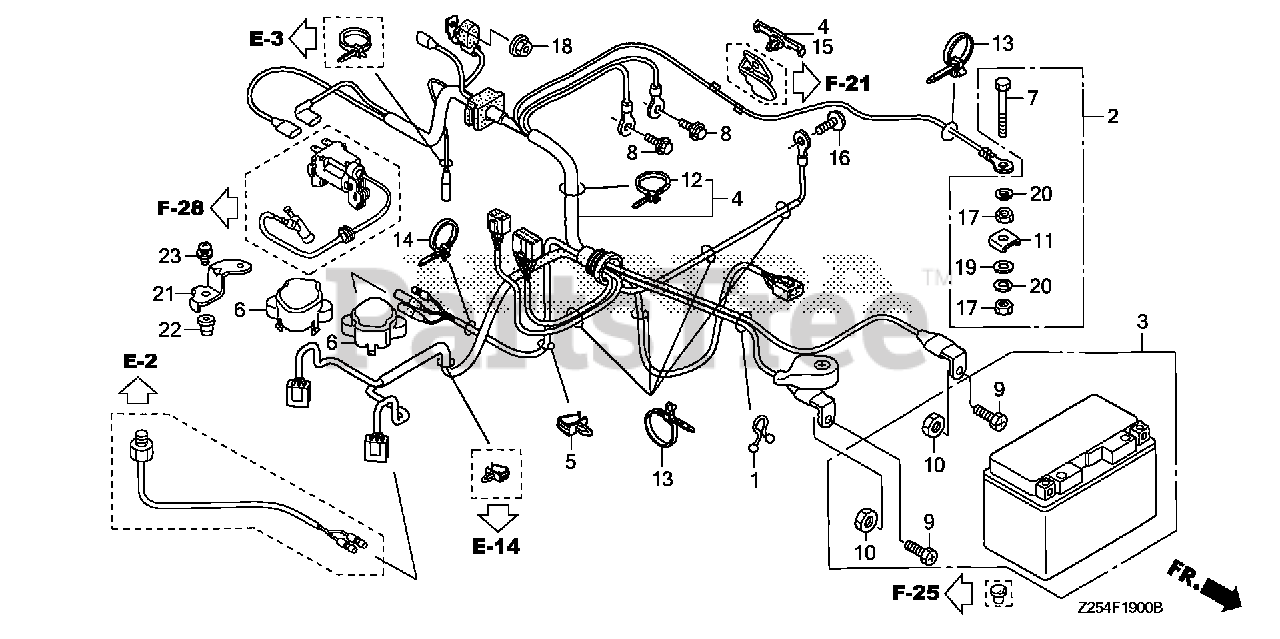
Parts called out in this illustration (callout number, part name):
1	CLAMP, FUEL HOSE (18.5MM)
2	TERMINAL SET, GROUND
3	BATTERY (YTZ14S) (YUASA) (MSDS)
4	WIRE HARNESS ASSY., ENGINE
5	CLIP B, HARNESS
6	COVER, THROTTLE MOTOR
7	BOLT, HEX. (6X28)
8	BOLT, FLANGE (6X12) (CT200)
9	BOLT, BATTERY TERMINAL
10	NUT, BATTERY TERMINAL
11	RETAINER (6MM)
12	STRAP, CABLE (118MM) (BLACK)
13	STRAP, CABLE (105MM) (BLACK)
14	CLIP B, HARNESS BAND (129.4MM) (DARK BROWN)
15	CLIP, WIRE HARNESS (50MM) (BLACK)(HARNESS TAPING)
16	SCREW, PAN (5X8)
17	NUT, HEX. (6MM)
18	NUT-WASHER (8MM)
19	WASHER, PLAIN (6MM)
20	WASHER, SPRING (6MM)
